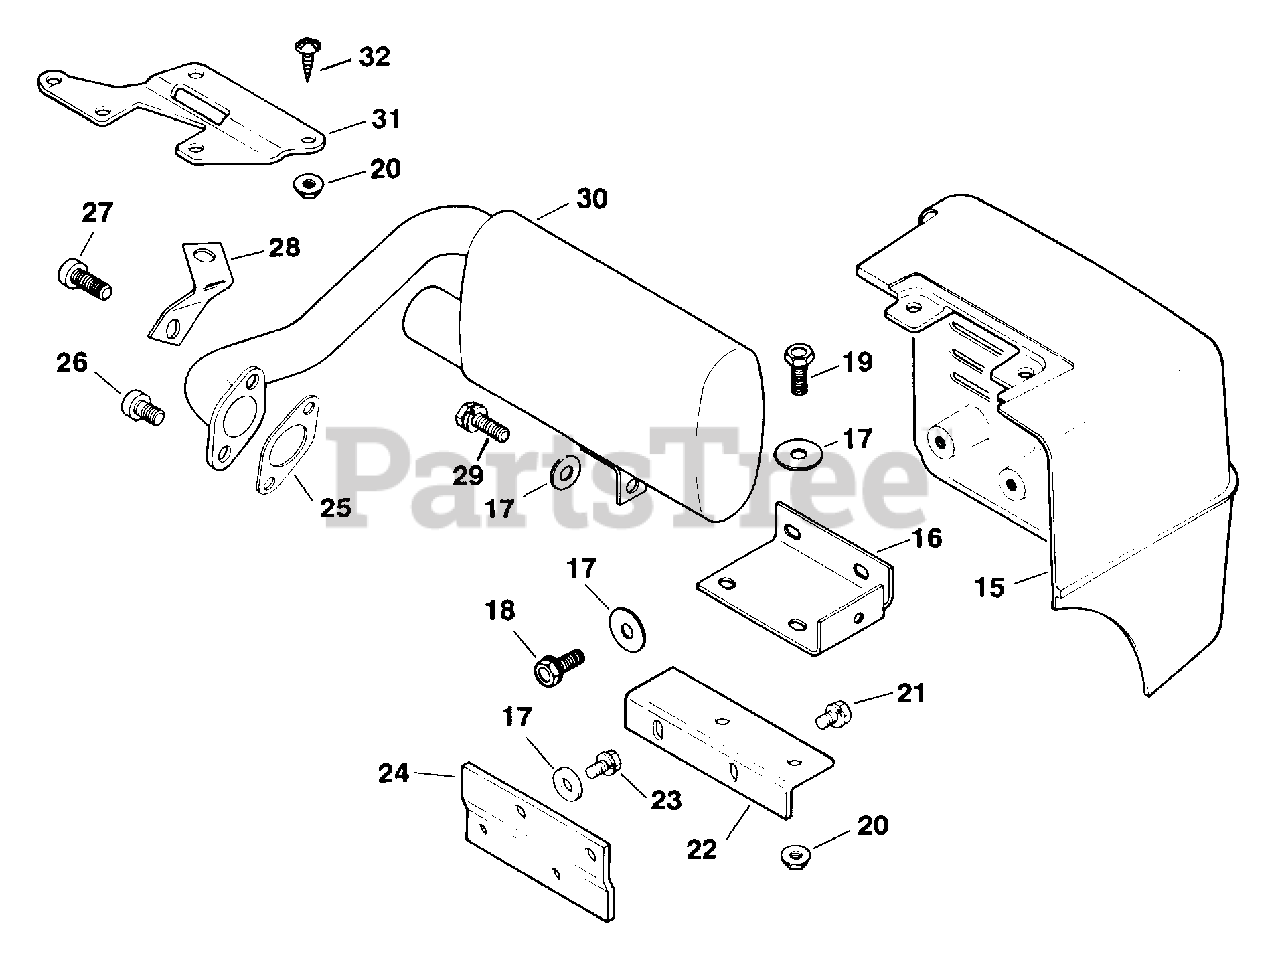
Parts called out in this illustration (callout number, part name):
15	COVER - DISCONTINUED
16	BRACKET - DISCONTINUED
17	WASHER, FLAT 1/4" (O.D. 5/8")
19	SCREW, SEMS 1/4-20X5/8" USE 25 086 539-S
20	PALNUT, 1/4-20
22	BRACKET - DISCONTINUED
26	SCREW - DISCONTINUED
27	SCREW, HEX SOCKET HEAD CAP USE 25 086 87-S
28	BRACKET-DISCONTINUED
29	SCREW, SEMS 1/4-20-1/2"
30	MUFFLER - DISCONTINUED
